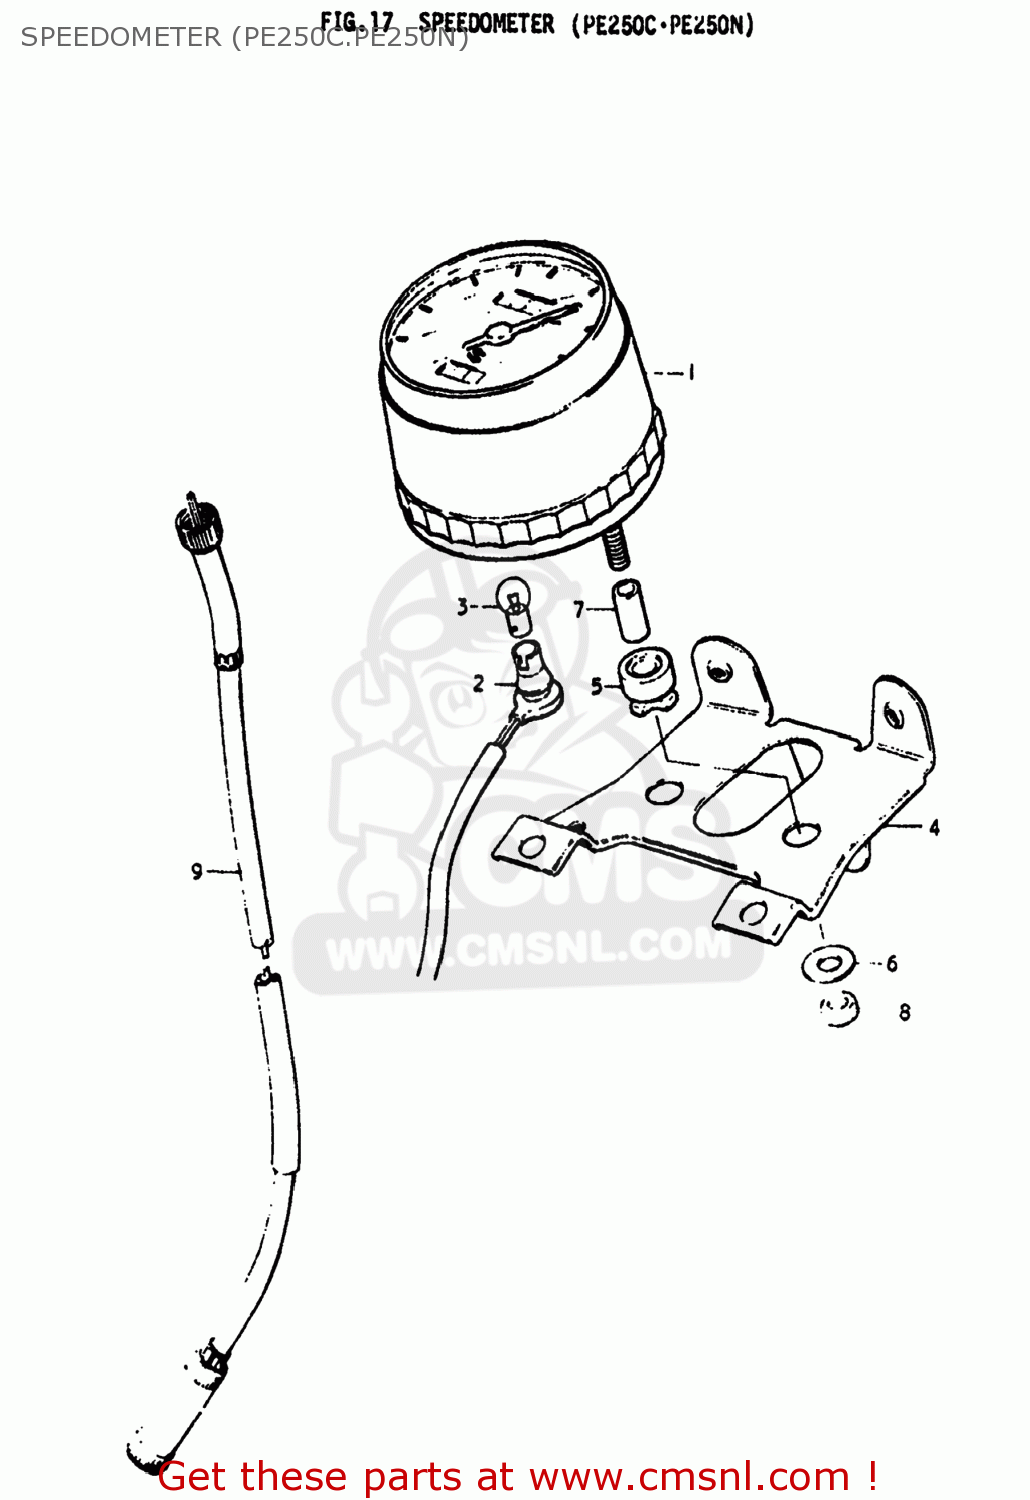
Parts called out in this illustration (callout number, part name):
0	SPEEDOMETER ASSEMBLY
1	SPEEDOMETER ASSEMBLY
2	SOCKET,METER
3	BULB(6V1.7W,STANLEY,A61A)
4	BRACKET,METER
5	CUSHION,METER NO.1
6	WASHER
7	SPACER,METER
8	NUT
9	CABLE ASSEMBLY,SPEEDOMETER
